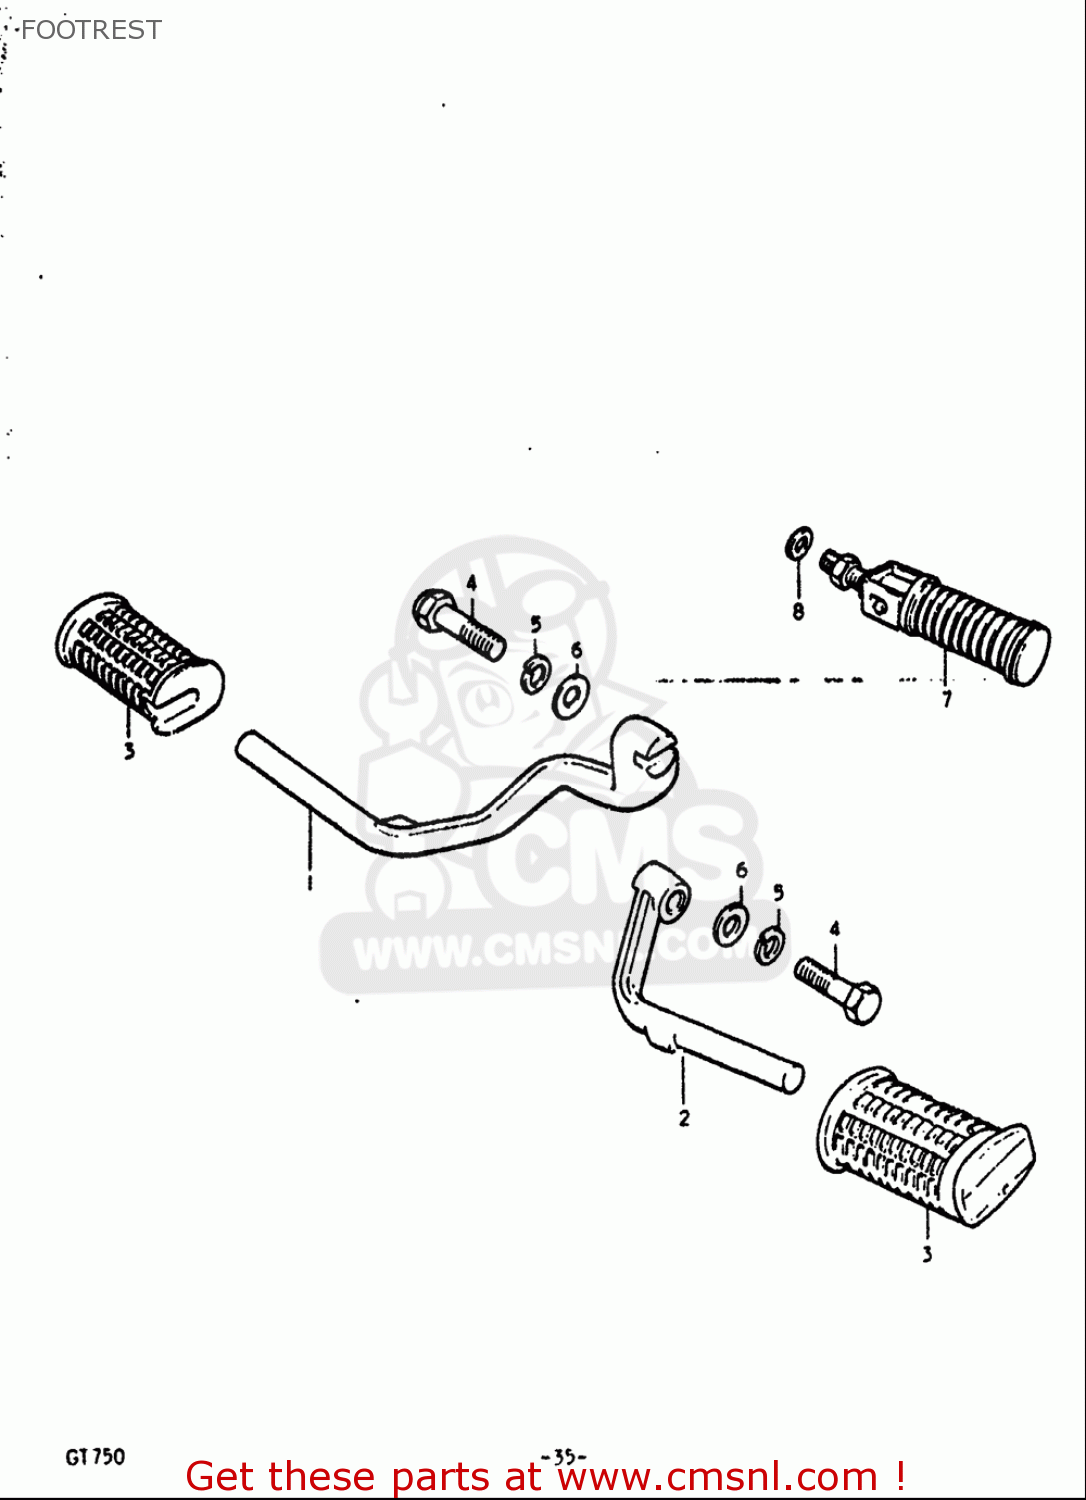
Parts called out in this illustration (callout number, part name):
5	WASHER,LOCK
6	WASHER
7	FOOTREST ASSY,PILLION
8	WASHER
